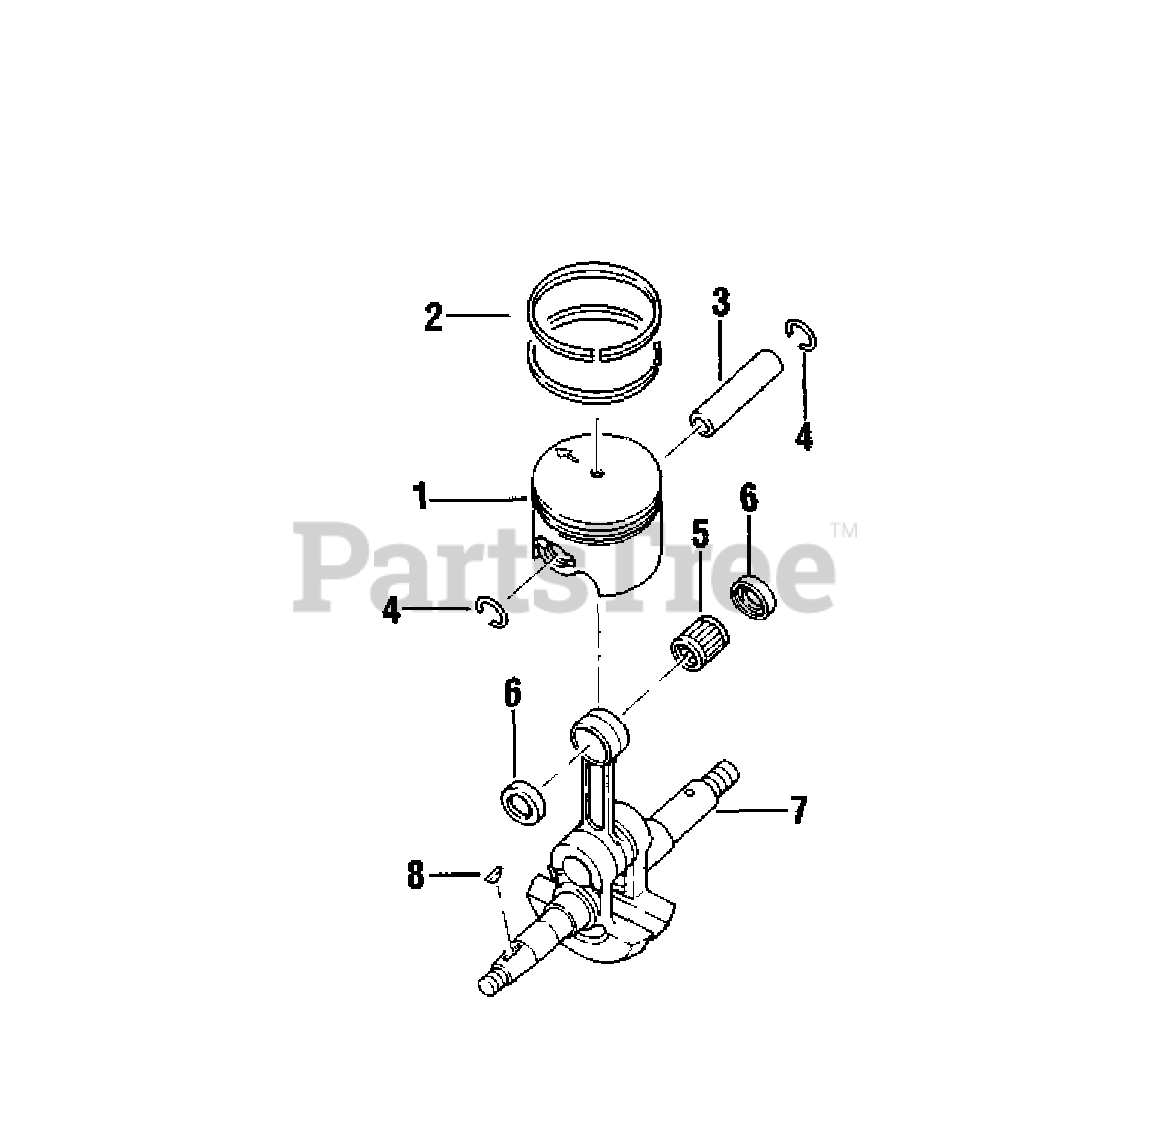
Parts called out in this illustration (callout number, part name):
1	PISTON
2	RING, PISTON
2	GASKET, CYLINDER
3	PIN, PISTON
4	RING, RETAINING
5	BEARING, NEEDLE
7	CRANKSHAFT ASSY
8	KEY, WOODRUFF - 3×10
